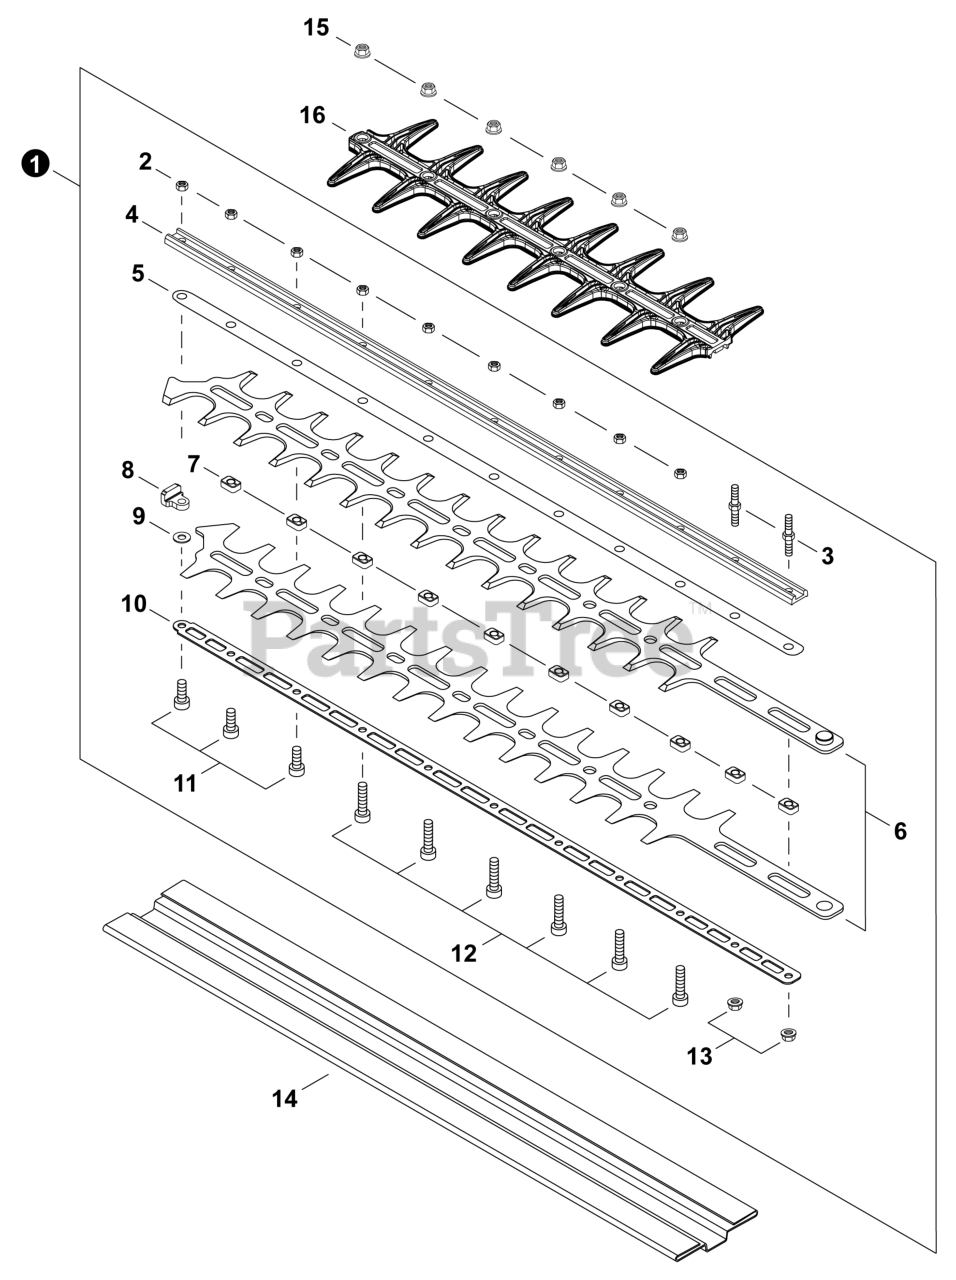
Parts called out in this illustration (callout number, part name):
1	CUTTER ASSY, 24"
3	STUD, MOUNTING M5×36
4	SUPPORT, BLADE 24"
5	SUPPORT, BLADE 24"
6	CUTTER 24"
10	SUPPORT, BLADE 24"
11	BOLT, TORX 5×16
12	BOLT, TORX 5×25
13	NUT, FLANGE M5
14	SCABBARD
15	NUT, FLANGE M5
16	GUARD, CUTTER BLADE
